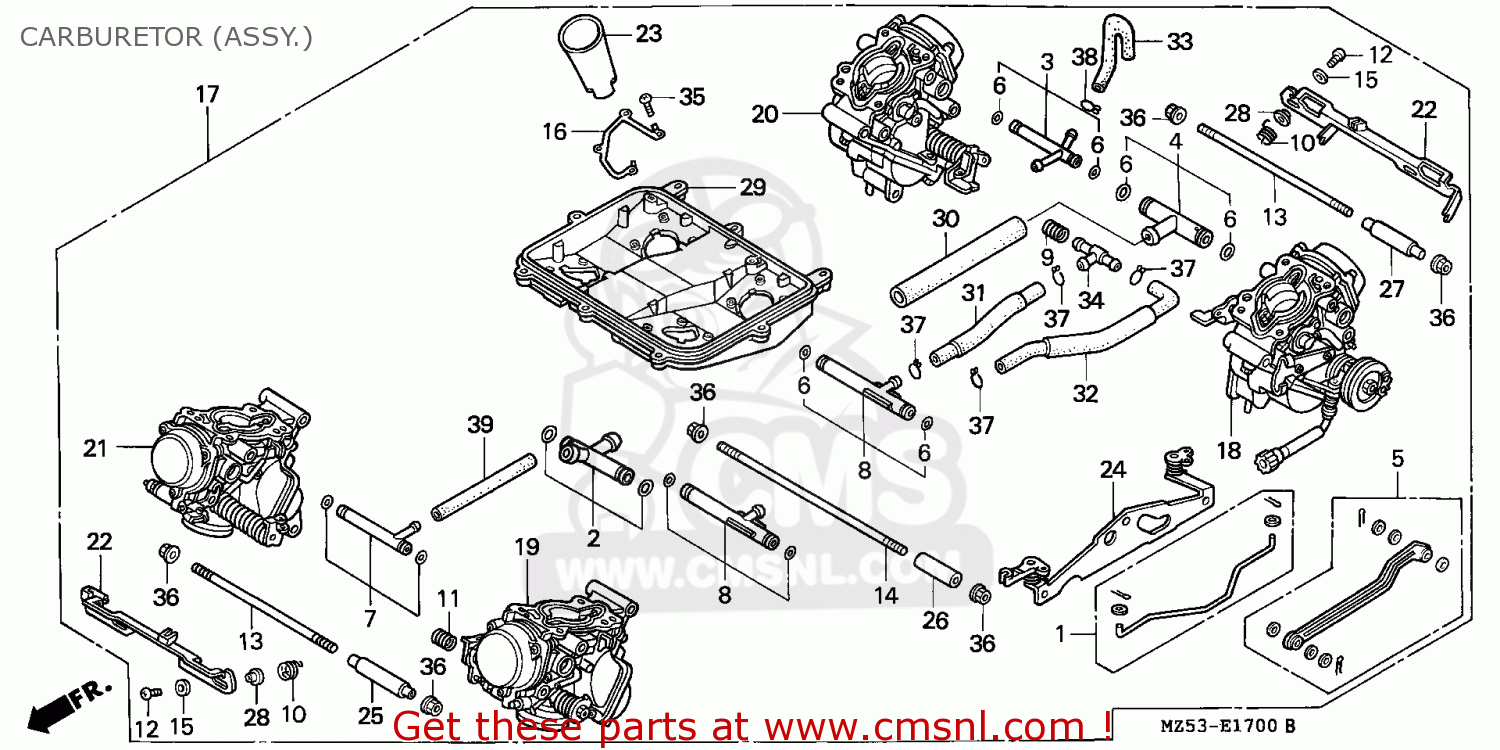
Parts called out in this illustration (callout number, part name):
1	LINK ROD SET
2	JOINT SET
3	JOINT SET,FUEL
4	JOINT SET
5	LINKLEVER SET
6	GASKET SET,B
7	JOINT SET,FUEL
8	JOINT SET
9	COMPRN.COIL SPG.
10	COMPRN.COIL SPG.
11	SPRING
12	WASHER,SCREW
13	BOLT
14	BOLT
15	WASHER,PLAIN
16	WASHER
17	CARBURETOR ASSY.
18	CARBURETOR ASSY #
19	CARBURETOR ASSY #
20	CARBURETOR ASSY #
21	CARBURETOR ASSY #
22	LEVER,STARTER
23	FUNNEL,AIR
24	STAY COMP,JOINT
25	COLLAR
26	COLLAR
27	COLLAR
28	COLLAR
29	BASE,AIR CLEANER
30	TUBE,15X170
31	TUBE COMP,FUEL
32	TUBE COMP.,FUEL
33	TUBE
34	T JOINT
35	SCREW,CROSS 4X16
37	CLIP B1 12,TUBE
38	CLIP B1 12.5,TUBE
39	TUBE,7X140
